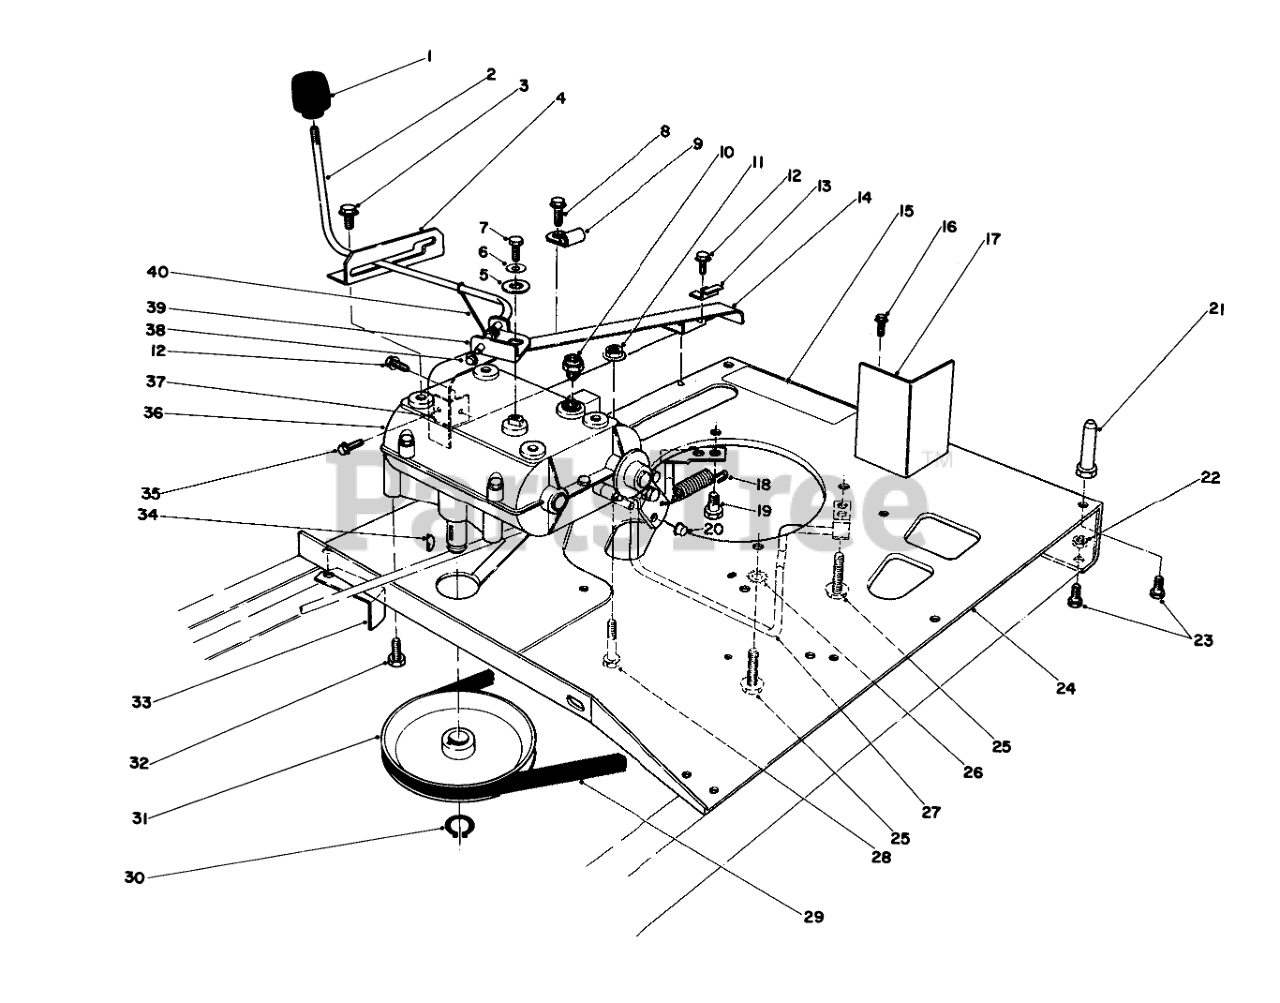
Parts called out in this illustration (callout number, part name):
2	SHIFT LEVER
3	SCREW-HHF
4	SHIFT LEVER GATE
5	WASHER-FLAT
6	WASHER-BELLEVILLE
7	SCREW-HH
8	SCREW-HHFTF
9	CLIP-FUEL LINE
10	NEUTRAL SWITCH
11	NUT-HF
12	SCREW
13	Clamp-Cable
14	Chain Guard
15	Decal
16	SCREW-HH
17	Baffle-Carb
18	SPRING-RETURN, BRAKE
19	Screw-HH
20	PUSH ON SPEED NUT 1/4
21	PIN-MOUNTING, LOWER
22	NUT-LOCK, CONE
23	SCREW-HH
24	Plate-Engine
25	SCREW-HWHTF
26	WASHER-LOCK
27	Belt Guide
28	SCREW-HH
29	V-BELT
30	RING-SNAP, EXTERNAL
31	PULLEY
32	5/16-18 X 5/8 SEMS SC
33	TRANS BELT RET B
34	KEY-WOODRUFF
35	SCREW-HWHTF
36	TRANSMISSION
37	CHAIN GUARD BRKT B
38	RETAINER-PUSH ON
39	SHIFT LEVER CLAMP
40	Spring-Shift Rod
